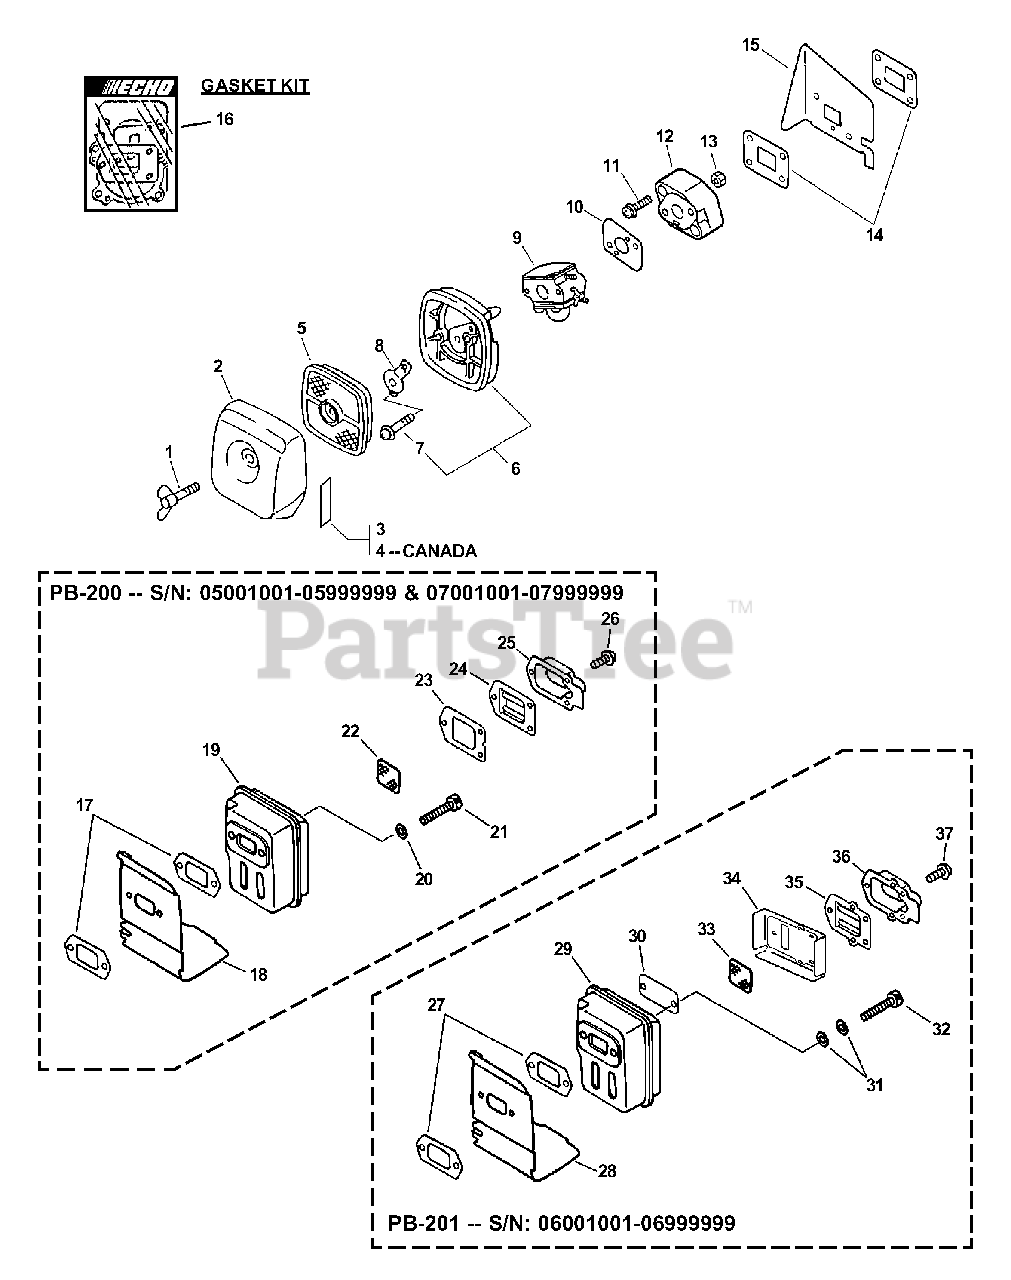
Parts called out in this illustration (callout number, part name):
1	BOLT, WING 5×20
2	COVER, AIR FILTER - GRAY
3	LABEL, CHOKE
4	LABEL, CHOKE
5	FILTER, AIR - SINGLE LAYER
6	AIR FILTER CASE ASSY
7	SCREW 5×65
8	PLATE, PREVENT
9	CARBURETOR - C1U-K68
10	GASKET, INTAKE
11	SCREW 5×22
12	INSULATOR, INTAKE
13	NUT M5
14	GASKET, INTAKE
15	HEAT SHIELD, INTAKE
16	GASKET KIT
17	GASKET, EXHAUST
18	COVER, MUFFLER
20	WASHER, FLAT 5.5×10×0.8
21	BOLT 5×55
22	SCREEN, SPARK ARRESTER
23	GASKET, EXHAUST
24	GUIDE, EXHAUST
25	GUIDE, EXHAUST - INNER
26	SCREW 4×10
27	GASKET, EXHAUST
28	COVER, MUFFLER
29	MUFFLER
30	PLATE, EYE
31	CONICAL WASHER
32	BOLT 5×55
33	SCREEN, SPARK ARRESTER
34	GASKET, EXHAUST
35	GUIDE, EXHAUST - INNER
36	GUIDE, EXHAUST - INNER
37	SCREW 4×12
